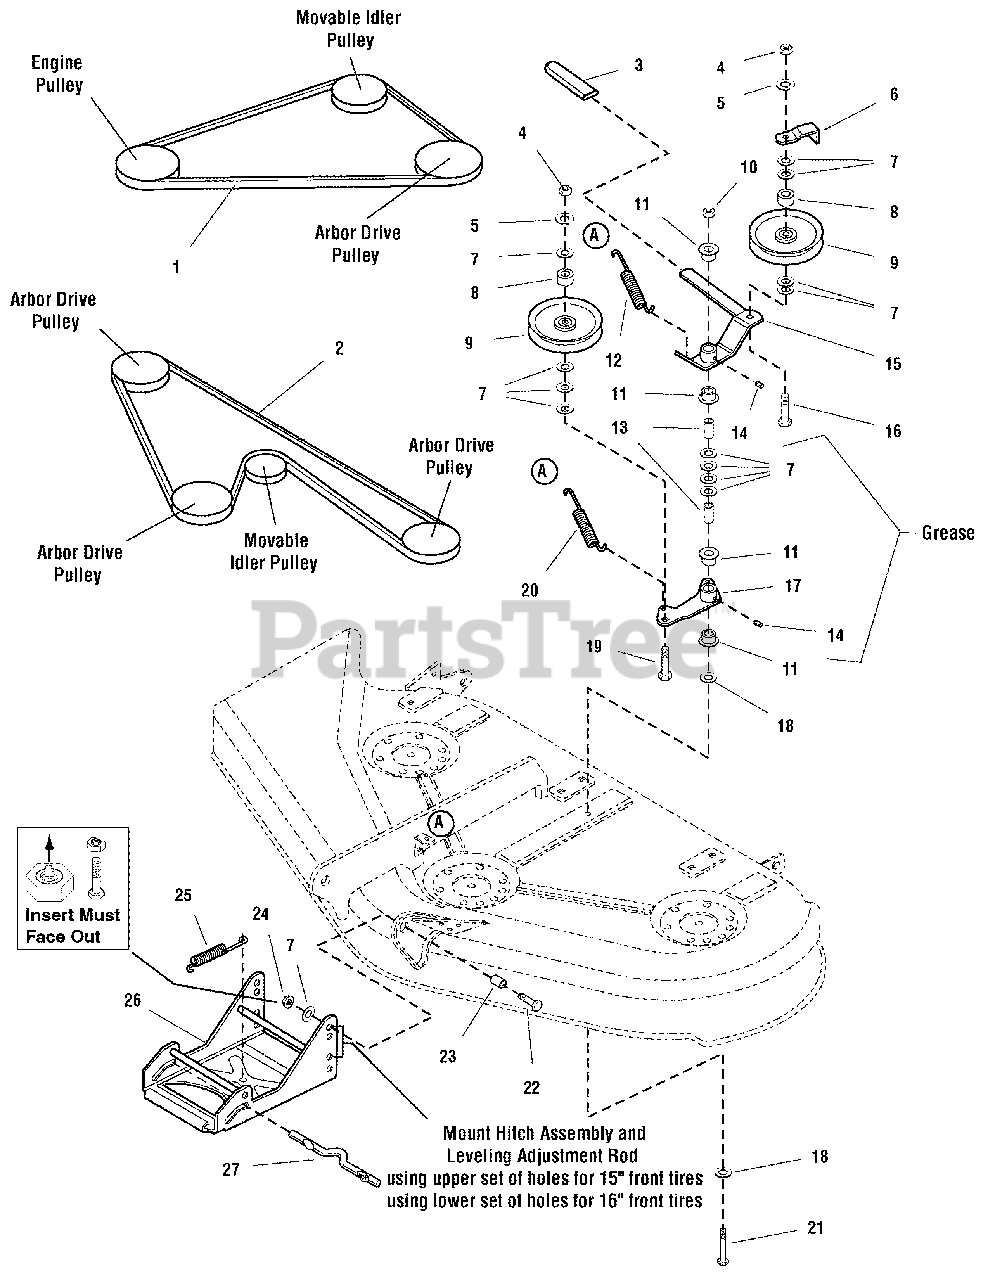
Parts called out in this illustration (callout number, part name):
1	V-BELT, Mower Drive
2	V-BELT, Arbor Drive
3	GRIP, Lever
4	NUT, Hex, 3/8-16
5	WASHER, Lock, 3/8
6	BELT STOP, Idler
7	WASHER, 3/8
8	SPACER, 25/64 x 21/32 x 7/16, Powder Metal
9	PULLEY, Idler, (Includes Ref. No. 8)
10	NUT, Hex Flange, 3/8-16, MAC Lock Large, Black
11	BUSHING, 5/8 x 3/4 x 13/32, Powder Metal
12	SPRING
13	SPACER, 25/64 x 5/8 x 1-1/8, Case Hardened
14	GREASE FITTING
15	LEVER ASSEMBLY, Idler, (Includes Ref. Nos. 11 & 14)
16	CARRIAGE BOLT, 3/8-16 x 2
17	LEVER ASSEMBLY, Idler Arm, (Includes Ref. Nos. 11 & 14)
18	WASHER, 3/8, Black
19	CARRIAGE BOLT, 3/8-16 x 1-1/2
20	SPRING
21	CAPSCREW, Hex Head, 3/8-16 x 3-1/2
22	CAPSCREW, Hex Head, 3/8-16 x 1-3/8
23	SPACER, 3/8 x 3/4 x 1/2
24	NUT, Hex Aluminum Insert Lock, 3/8-16
25	SPRING
26	HITCH ASSEMBLY
27	ROD, Latch
